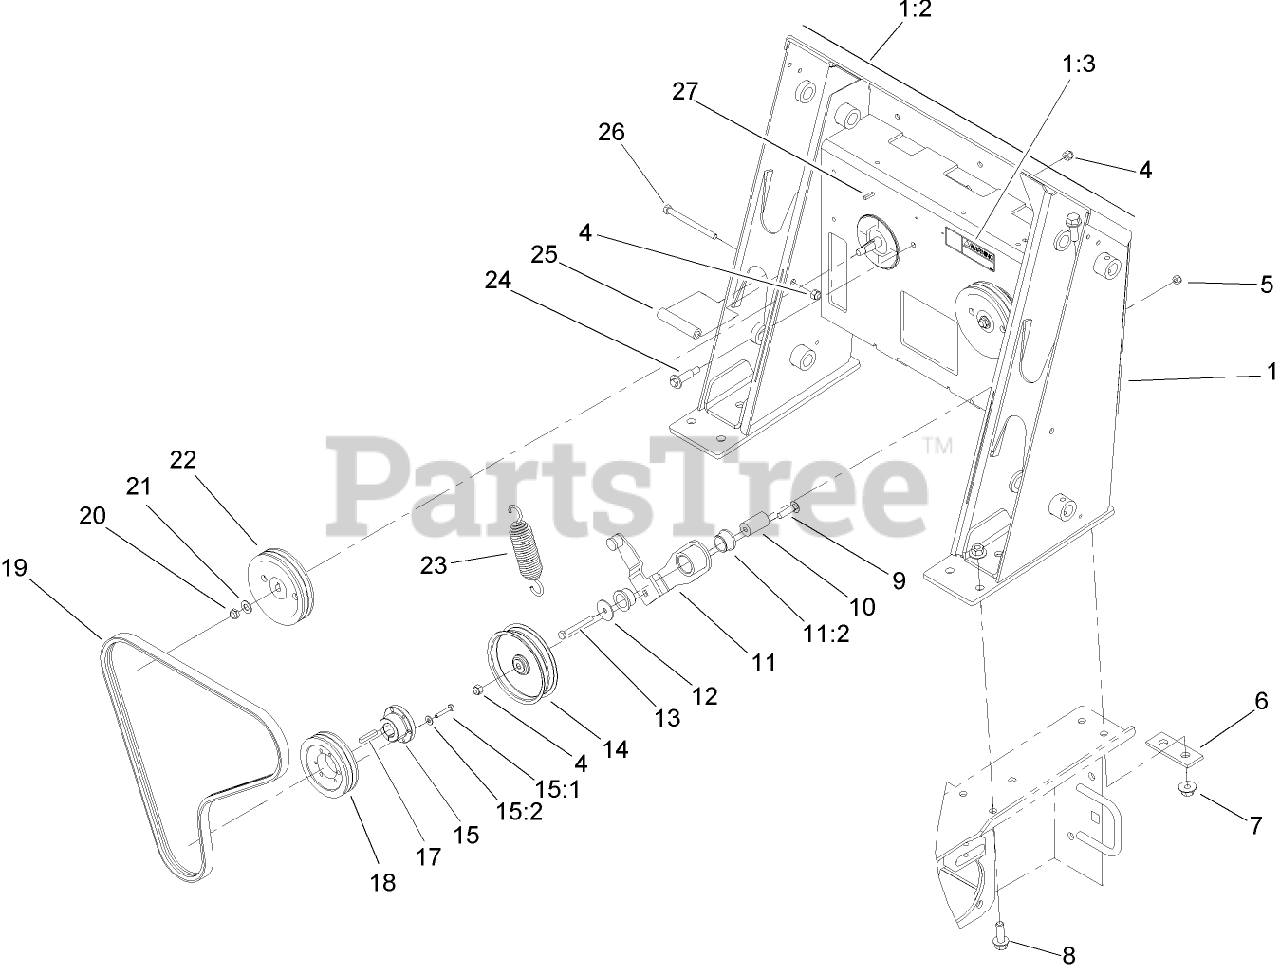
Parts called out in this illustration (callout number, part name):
1	LOADER TOWER ASM
1:2	DECAL-PANEL, CONTROL
1:3	DECAL-WARNING
4	NUT-LOCK, NI
5	NUT-LOCK, NI
6	PLATE-STIFFENER
7	NUT-LOCK, FLANGE
8	SCREW-HHF
9	SCREW-CARR
10	SPACER-MOUNTING
11	IDLER ARM ASM
11:2	BUSHING-FLANGE
12	WASHER-FLAT
13	SCREW-HH
14	PULLEY-IDLER
15	BUSHING
15:1	SCREW-HH
15:2	WASHER-LOCK / SP
17	KEY-SQUARE
18	PULLEY
19	V-BELT
20	NUT-LOCK, NI
21	WASHER-FLAT
22	PULLEY
23	SPRING-EXTENSION
24	BOLT-WHEEL
25	TUBE-SPACER
26	SCREW-HH
